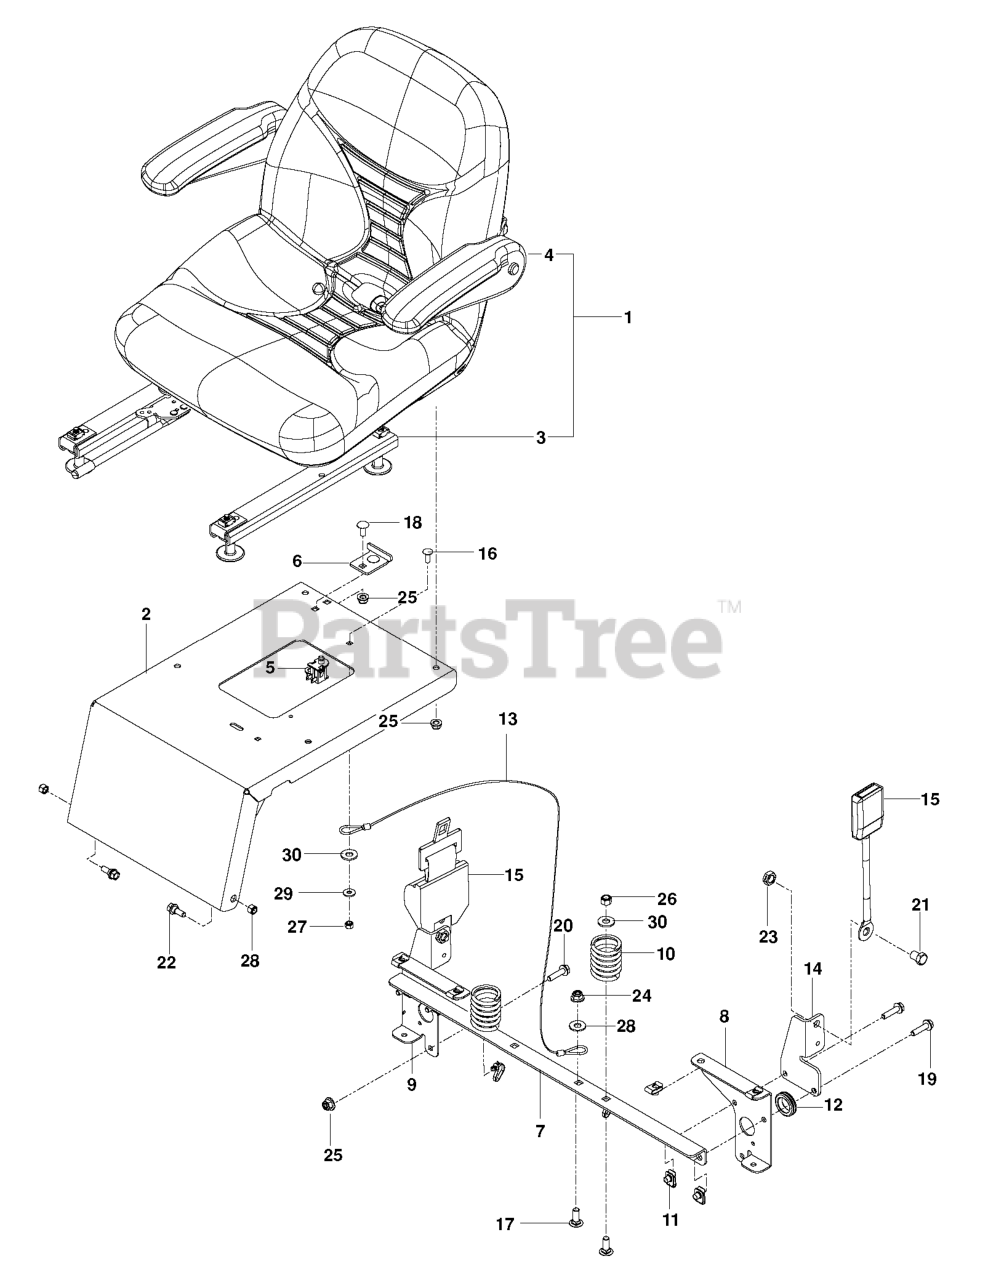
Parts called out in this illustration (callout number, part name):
1	SEAT
2	KIT.SEAT.MOUNT.W/DECAL
3	TRACK ADJUSTMENT KIT
4	ARMREST KIT, LT SQUARE END
5	SWITCH.SNAPMOUNT.NC
6	STOP, SEAT - BLACK
7	SUPPORT, SEAT
8	SUPPORT, LT, BLK
9	SUPPORT, RT, BLK
10	SPRING COMPRESSION
11	U-CLIP 5/16-18 NUT RETAINER
12	RUBBER GROMMET
13	SEAT LANYARD
14	MOUNT.SEAT.BELT.BLACK
15	SEAT BELT, RETRACTABLE
16	RHSNB 1/4C X 3/4
17	RHSNB 3/8C X 1
18	RHSNB 5/16-18 X 3/4
19	HHFS 5/16-18 X 1.25 TPBLT GD 5
20	HHFS 5/16-18 X 3/4
21	HCS 7/16-20 X .75 GD 5
22	SB 5/16-18 HEX HD GD5, BLK ZN
23	NUT HEX 7/16F LOCK RP
24	NUT 3/8-16 HEX FLG NYLOC ZD
25	5/16-18 NYLOC FLANGE NUT
26	NUT 3/8-16 NYLOC
27	NUT.1/4-20.HEX.NYLOC.ZD
28	NUT 5/16 NYLOC
29	WASHER 1/4 FLAT
30	WASHER 3/8 FLAT
